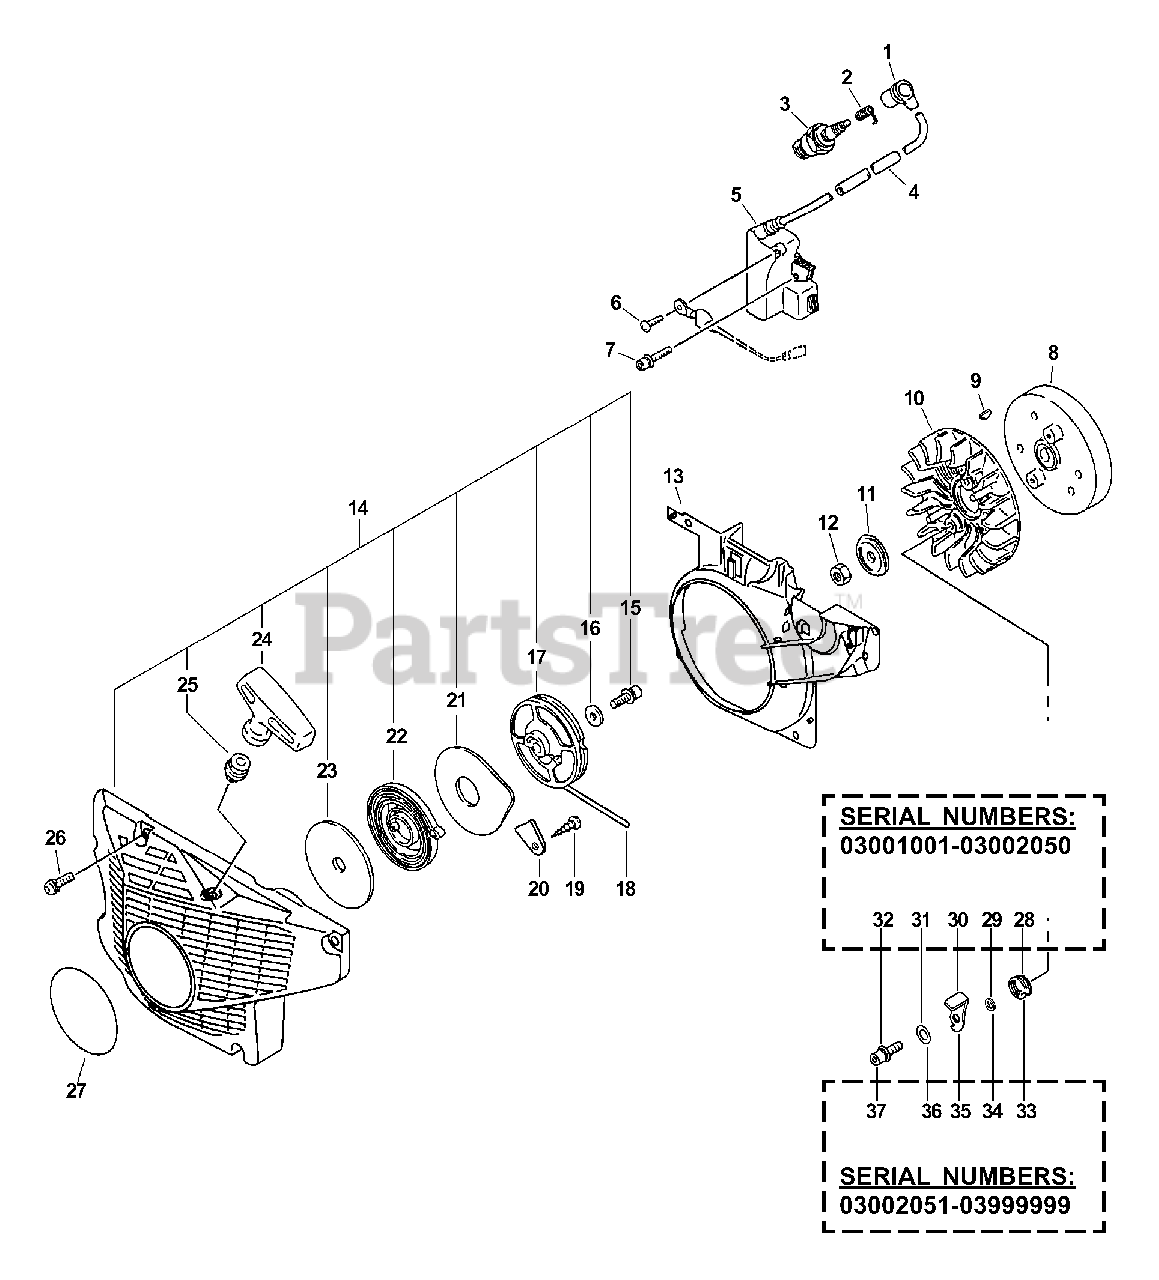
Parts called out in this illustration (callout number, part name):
1	CAP, SPARK PLUG
2	TERMINAL, SPARK PLUG
3	SPARK PLUG - BPM-7Y
5	COIL, IGNITION
6	SCREW 4×8
7	BOLT 4×20
8	FLYWHEEL
9	KEY, WOODRUFF
11	WASHER 8.2×31×0.8
13	COVER, FAN
14	STARTER ASSY
15	BOLT 5×14
16	WASHER 5.5×12×0.8
17	REEL, ROPE
18	ROPE, STARTER
19	SCREW 4×8
20	PLATE, EYE
21	PLATE, STARTER
22	SPRING, RECOIL
23	PLATE, STARTER
24	GRIP, STARTER
25	GUIDE, ROPE
26	BOLT 5×20
27	LABEL, ECHO
28	SPRING, RETURN
30	PAWL, STARTER
31	WASHER 5.5×12×0.8
32	BOLT 5×14
33	SPRING, RETURN
34	COLLAR 5
35	PAWL, STARTER
36	WASHER 5.5×12×0.8
37	BOLT 5×20
